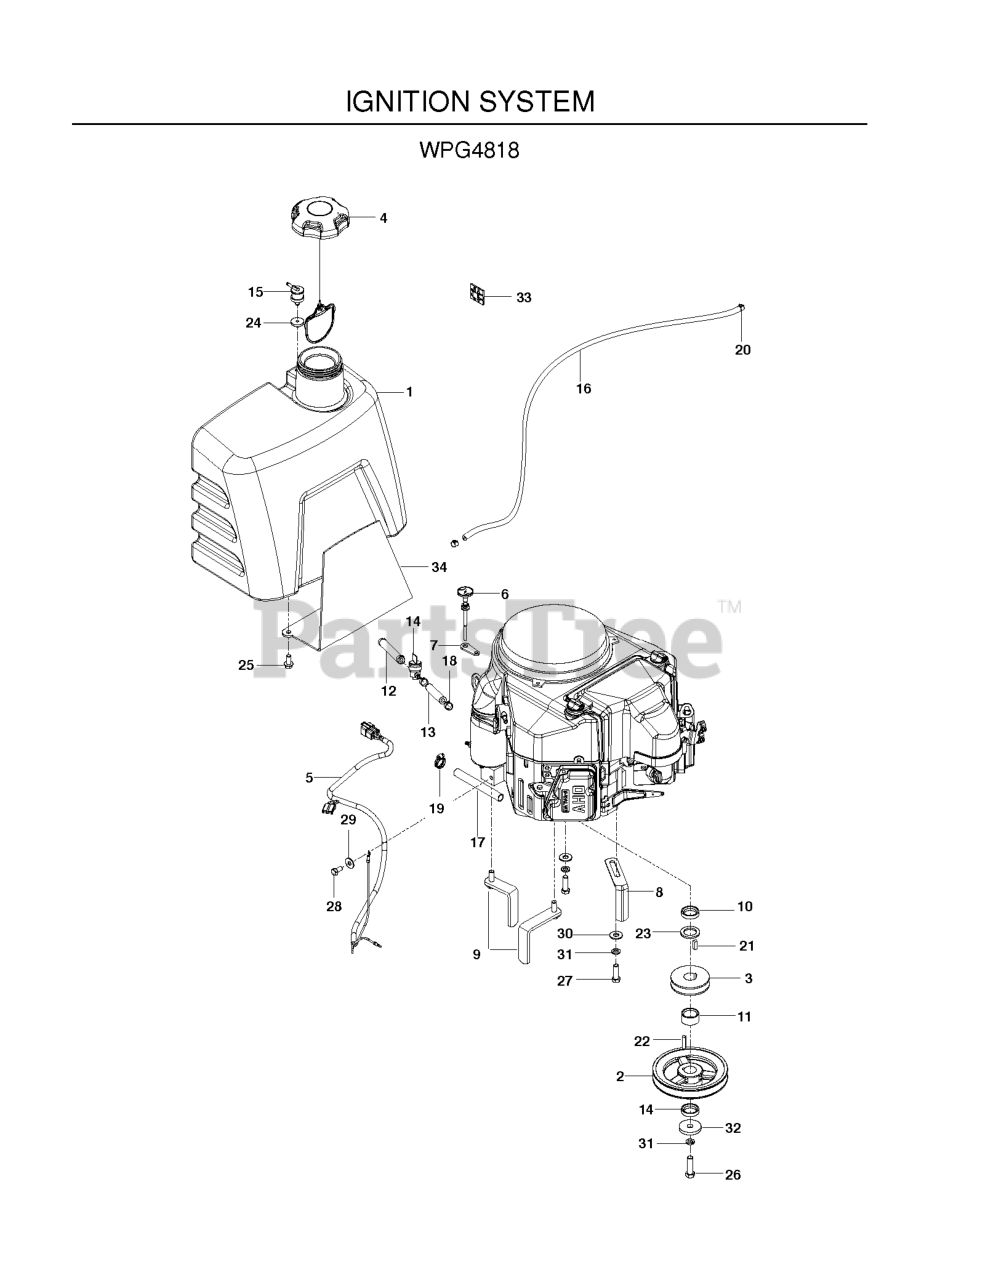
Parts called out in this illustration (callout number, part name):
1	TANK, FUEL BLK, WALK
2	PULLEY, ENGINE
4	CAP, FUEL
5	LOWER HARNESS
6	CABLE, CHOKE
7	SUPPORT, CHOKE BLK
8	BELT GUIDE - LONG
9	BELT GUIDE
12	FUEL LINE 5"
13	FUEL HOSE 3.5
14	FUEL VALVE
15	VALVE.FUEL.CHECK
16	HOSE, 3/16" VAPOR, 52"
17	HOSE, OIL DRAIN, 5"
18	HOSE CLAMP
19	HOSE CLAMP T-1865
20	CLAMP, HOSE
21	KEY 1/4 SQ X 3/4
22	KEY 1/4 SQ X 1 1/8
23	BUSHING, 10GA MACHINERY
24	GROMMET, CHECK VALVE
25	HHFS 5/16-18 X 3/4
26	HCS 7/16F X 1 1/2
27	HCS 3/8C X 1 1/4 GR5
28	HCS M8-1.25 X 16MM GR 5 ZD
29	WASHER 5/16 FLAT
30	WASHER 3/8 FLAT
31	SLW 3/8 STD
32	SPINDLE WASHER
33	MOUNTING BLOCK CABLE TIE
34	PLATE ID, ORANGE
